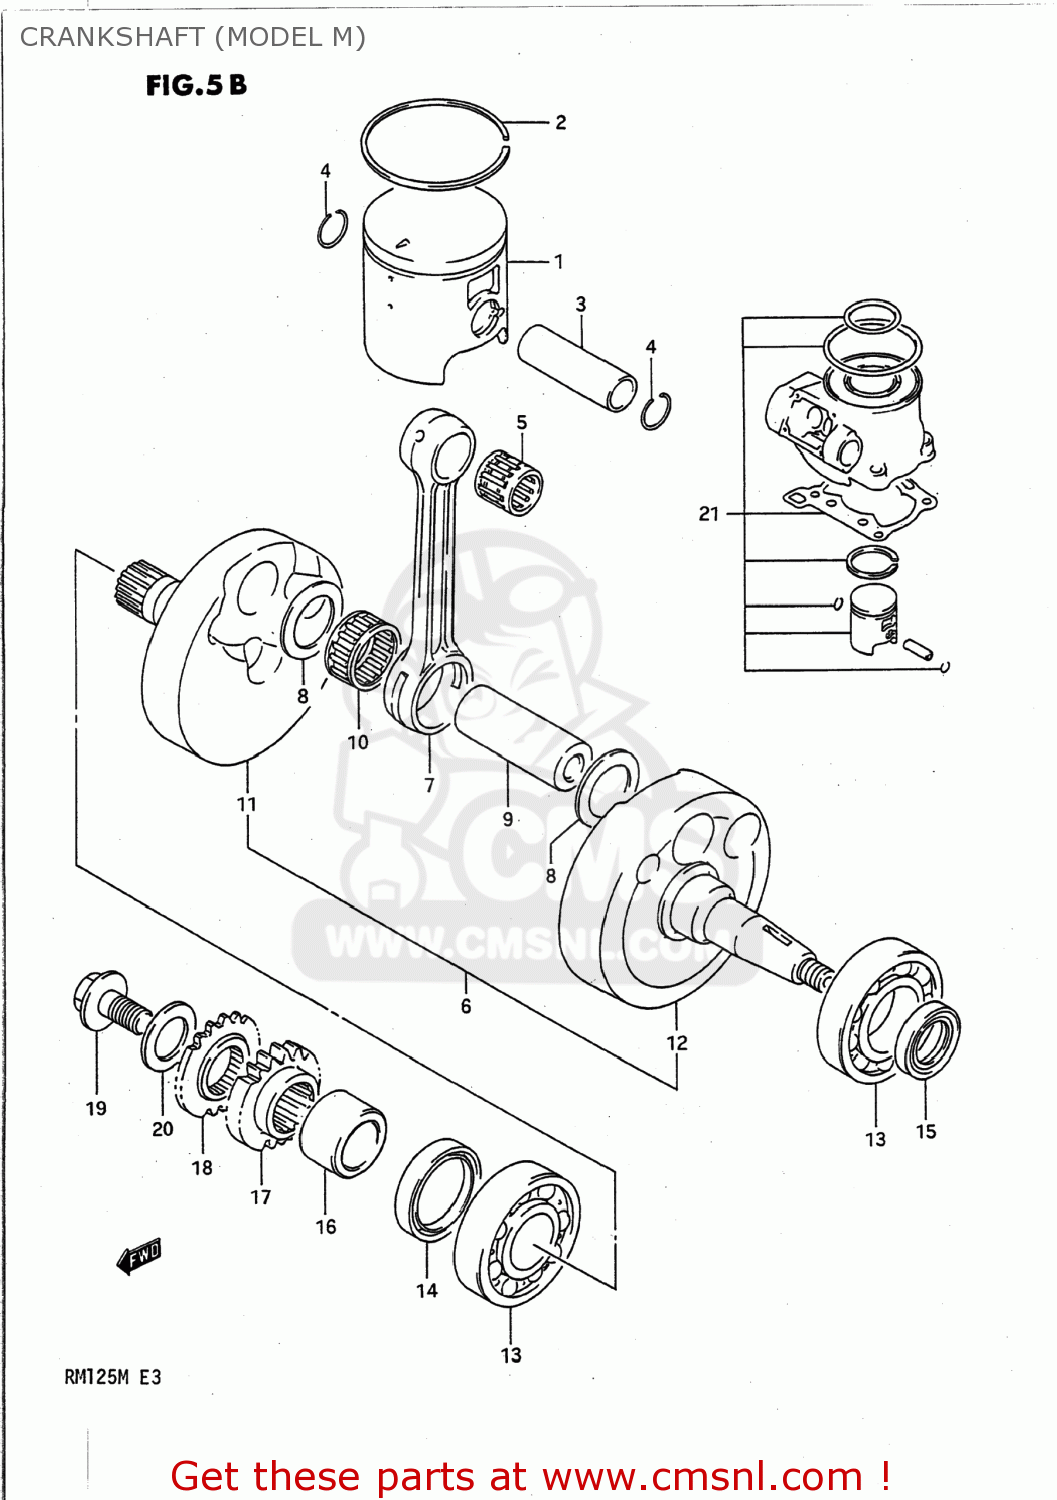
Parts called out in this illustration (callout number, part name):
1	PISTON
2	RING,PISTON
3	PIN,PISTON
4	CIRCLIP
5	BEARING(15X19X20)
6	CRANKSHAFT ASSEMBLY
7	ROD,CONNECTING
8	WASHER
9	PIN,CRANK
10	BEARING(22X28X16)
11	CRANKSHAFT
12	CRANKSHAFT,LEFT
13	BEARING
14	SEAL,OIL(30X40X7)
15	SEAL,OIL(18X30X6)
16	SPACER,PRIMARY DRIVE GEAR
17	GEAR,PRIMARY DRIVEN
18	GEAR, GOVERNOR DRIVE (NT:19)
19	BOLT,PRIMARY DRIVE GEAR
20	WASHER
21	PISTON SET
